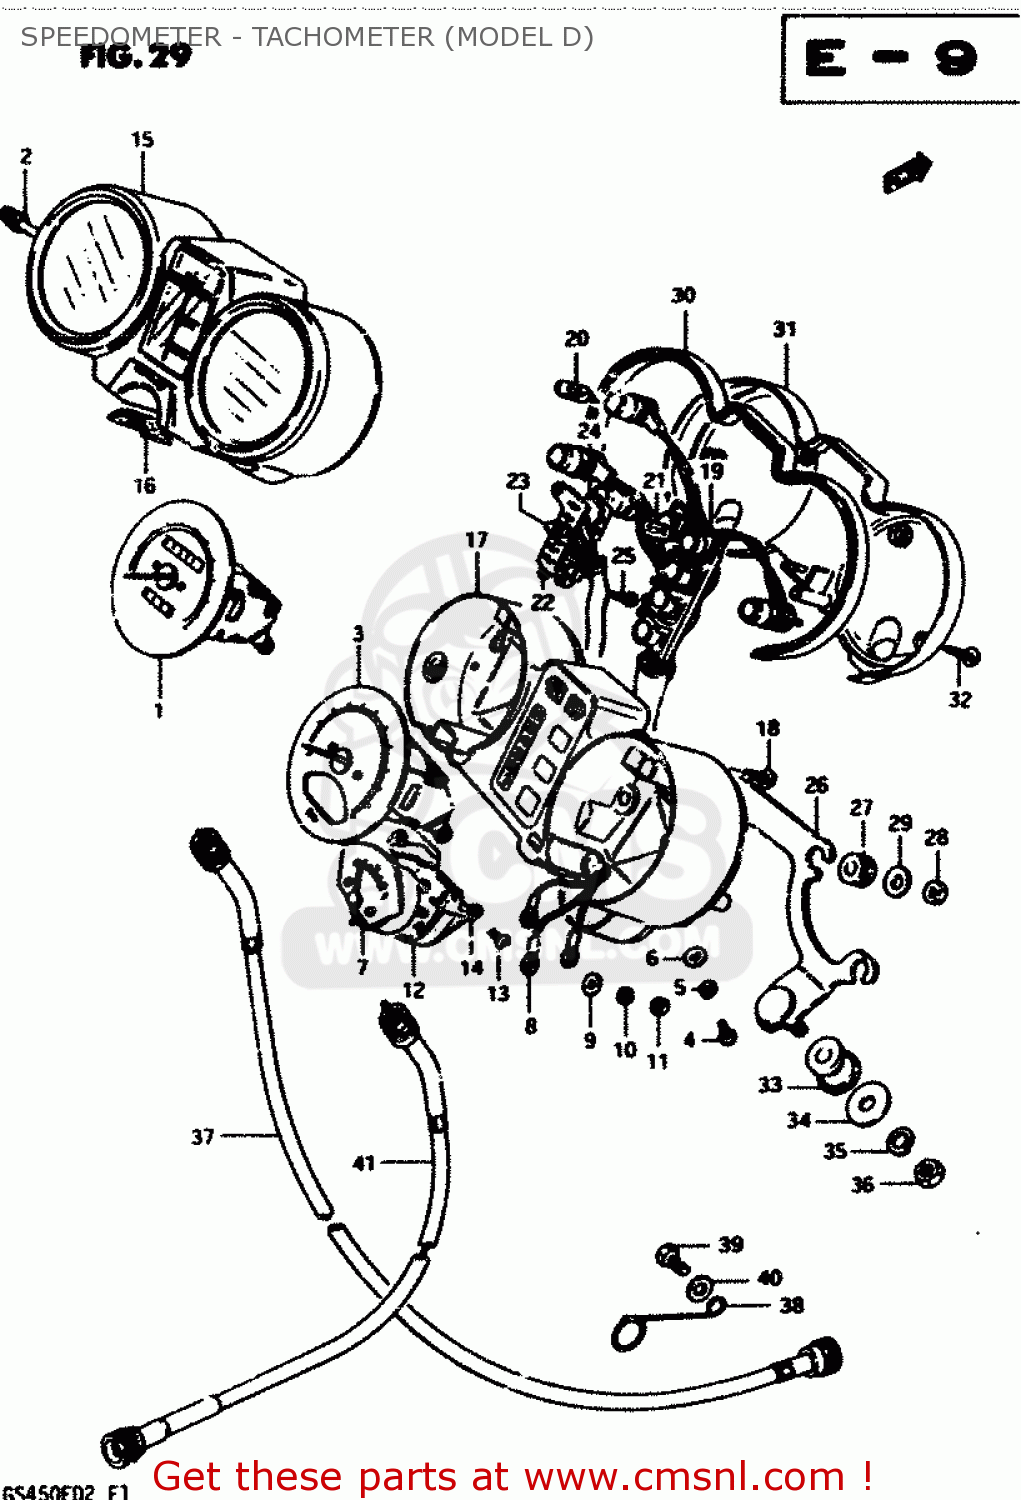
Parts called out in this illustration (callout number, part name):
1	SPEEDOMETER (KILO)
2	KNOB
3	METER,TACHOMETER
4	SCREW 4X10
5	WASHER
6	LOCK WASHER
7	METER,FUEL
8	WIRE,FUEL METER LEAD
9	WASHER,FUEL METER
10	LOCK WASHER
11	NUT 3MM
12	BRACKET,FUEL METER
13	SCREW
14	LOCK WASHER
15	HOOD,METER
16	SEAL,IGNITION SWITCH
17	CASE,METER,INNER
18	SCREW
19	SOCKET
20	BULB(12V3.4W,T10)
21	BULB(12V1.7W,T10,WB121)
22	SOCKET,GEAR INDICATOR
23	BULB(14V1.12W,BQ041-32503B)
24	COVER,INDICATOR,LOWER
25	SCREW
26	BRACKET,COMBINATION METER
27	CUSHION,METER
28	NUT
29	WASHER (5.5X16X1.2)
30	COVER,METER,UNDER
31	COVER,LWR
32	SCREW
33	CUSHION,METER BRACKET
34	WASHER (8.5X20X1.6)
35	LOCK WASHER
36	NUT
37	CABLE ASSY,SPEEDOMETER
38	CLAMP,SPEEDOMETER CABLE
39	BOLT, UPPER
40	WASHER
41	CABLE ASSEMBLY,TACHOMETER
